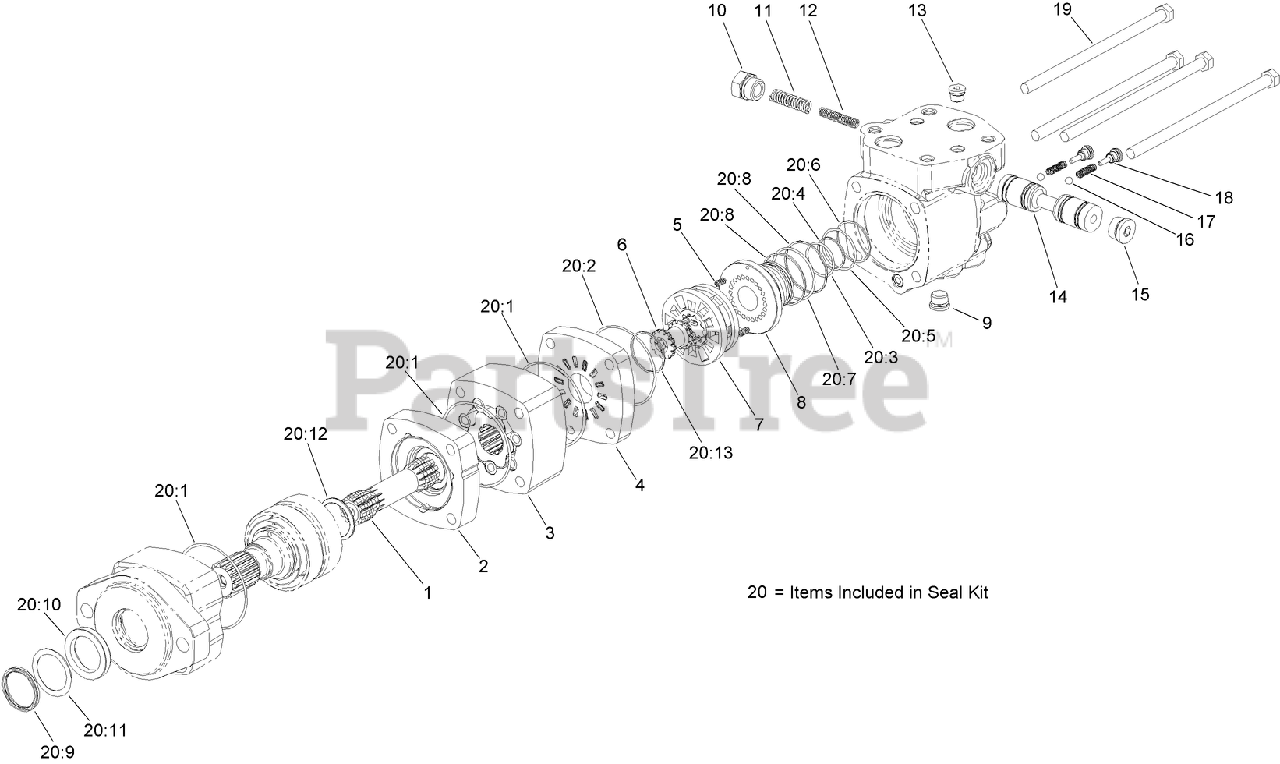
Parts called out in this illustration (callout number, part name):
1	SHAFT-DRIVE
2	PLATE-WEAR
3	GEROLER ASM
4	PLATE-VALVE
5	SPRING
6	DRIVE-VALVE
8	BALANCING RING ASM
9	PLUG ASM
10	PLUG ASM
11	SPRING-COMPRESSION
12	SPRING-COMPRESSION
13	PLUG ASM
14	SPOOL-CONTROL
15	PLUG ASM
16	BALL-STEEL
17	SPRING-COMPRESSION
18	PLUG ASM
19	SCREW-CAP
20	SEAL KIT
20:1	O-RING
20:2	O-RING
20:3	O-RING
20:4	RING-BACKUP
20:5	O-RING
20:6	RING-BACKUP
20:7	O-RING
20:8	RING-BACKUP
20:9	SEAL
20:10	SEAL
20:11	Washer-Backup
20:12	Seal-Shaft Face
20:13	SEAL
